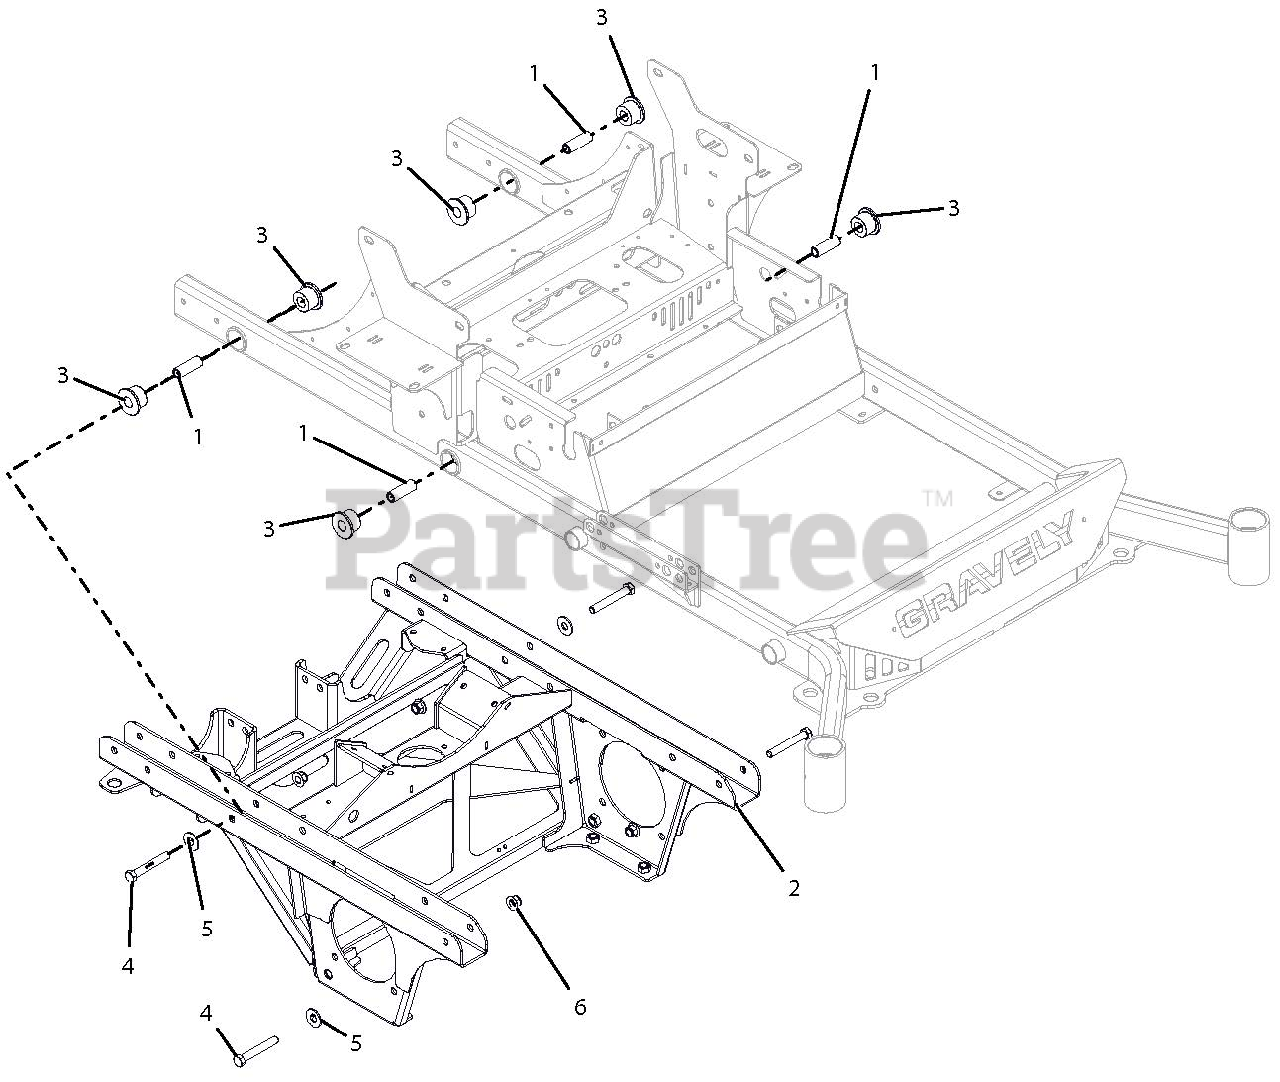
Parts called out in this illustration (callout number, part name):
1	SPCR, .50 X .75 X 2.23 YZ
2	WLDMT, ENGINE/ TRANSMISSION FRAME
3	BSHG, FLANGE .750 X 1.510 X 1.130 X 2.000
4	BLT-HEX .50-13X3.50 GR5 YWZC
5	WSHR-FL-STL.563X1.38X.109YWZC
6	NUT-LK-NYL-FLG .50-13 YWZC
